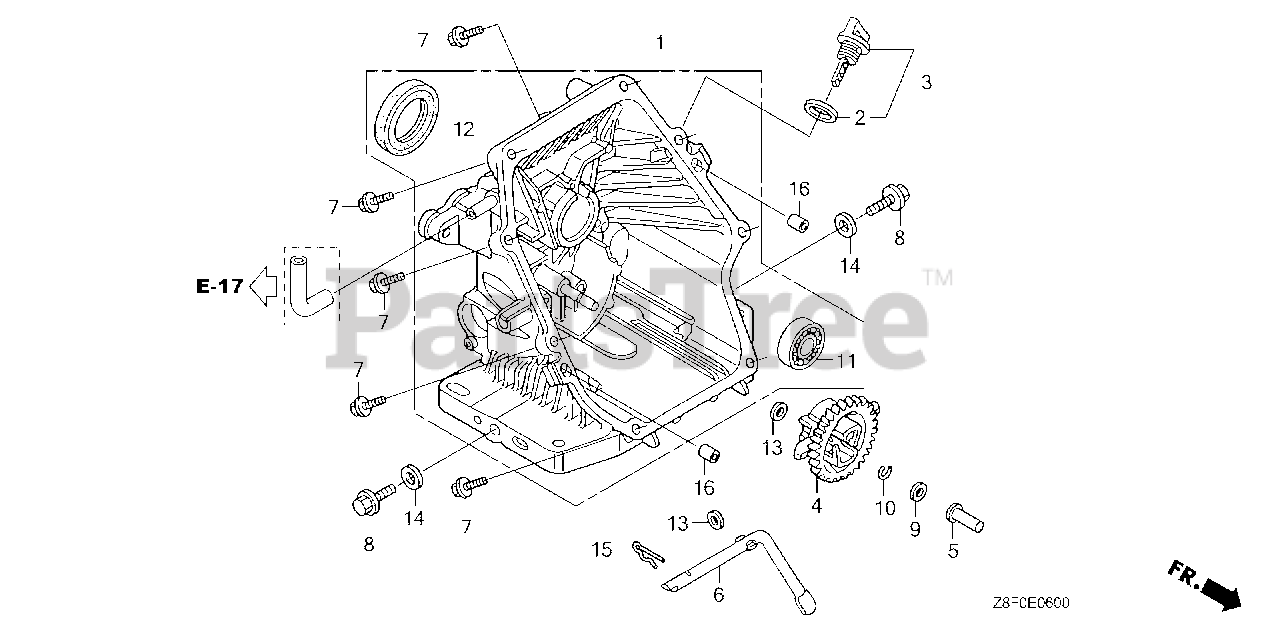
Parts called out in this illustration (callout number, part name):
1	COVER ASSY., CRANKCASE
2	GASKET, OIL FILLER CAP (NOT AVAILABLE)
3	GAUGE ASSY., OIL LEVEL
4	GOVERNOR ASSY.
5	SLIDER, GOVERNOR
6	SHAFT, GOVERNOR ARM
7	BOLT, FLANGE (6X26)
7	BOLT, FLANGE (6X25) Use up to Engine SN 2056819.
8	BOLT, DRAIN PLUG
9	WASHER, THRUST (6MM)
10	CLIP, GOVERNOR HOLDER
11	BEARING, RADIAL BALL (62/28)
12	OIL SEAL (28X41.25X6)
13	WASHER, PLAIN (6MM)
14	WASHER, DRAIN PLUG (12MM)
15	PIN, LOCK (8MM)
16	PIN, DOWEL (8X20)
